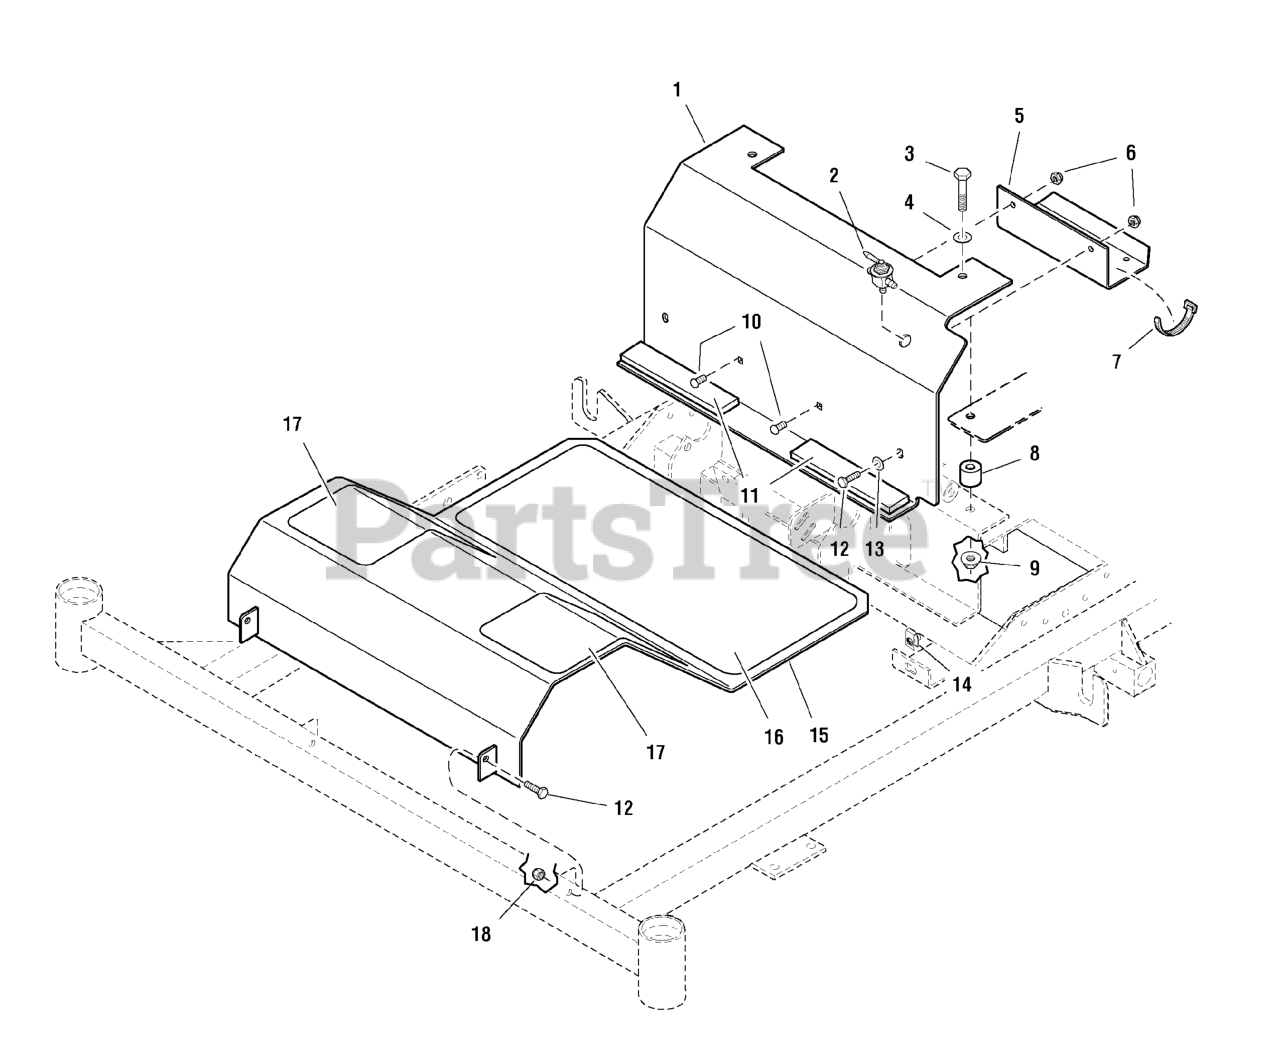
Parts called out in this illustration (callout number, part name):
1	BRAKE COVER PANEL ASSEMBLY
2	VALVE, Fuel Shut Off
3	BOLT, 3/8-16 X 2, GD5, CZ
4	WASHER, 3/8 SAE
5	FUEL LINE GUIDE
6	NUT, 1/4-20 HEX NYLON LOCK
7	TIE WRAP, 11"
8	SPACER, .39 x 1.00 x .88
9	NUT, 3/8-16 Hex Serrated Flange
10	BOLT,1/4-20X0.750,GR5,STD NECK,SQ,ZC/CL
11	RUBBER PAD
12	BOLT, 5/16-18 X 1 GD5 YZ
13	WASHER, 5/16" SAE
14	BODY CLIP, 5/16-18-7GA MATERIAL
15	FLOOR PLATE
16	SAFETY WALK, 11.50 X 19.00
17	SAFETY WALK
18	NUT, 5/16-18 Hex Nylon Lock
